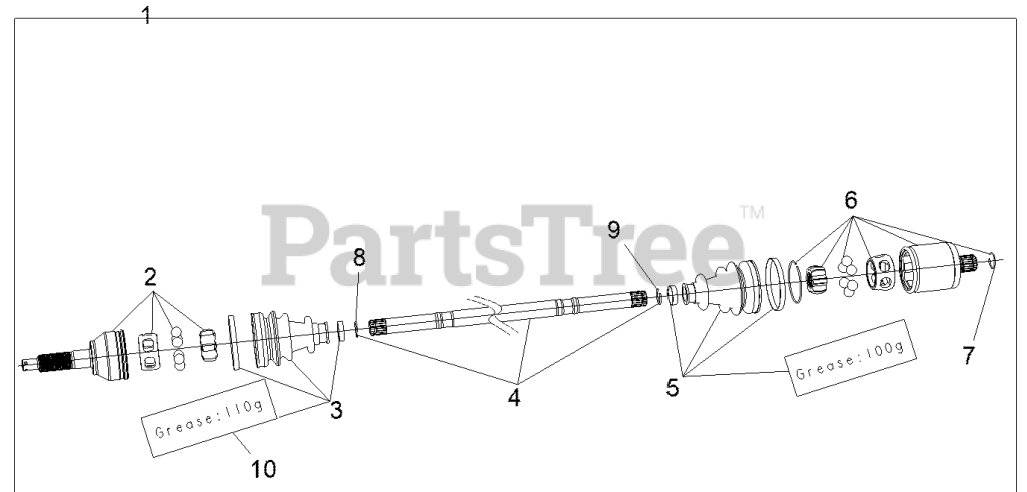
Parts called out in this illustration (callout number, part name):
1	ASM-HALFSHAFT,REAR
2	K-CV OUTER JOINT
3	KIT-BOOT(PR-8071)
4	BAR
5	K - BOOT, INNER
6	JOINT, INNER
10	GREASE(K575/VW738)
